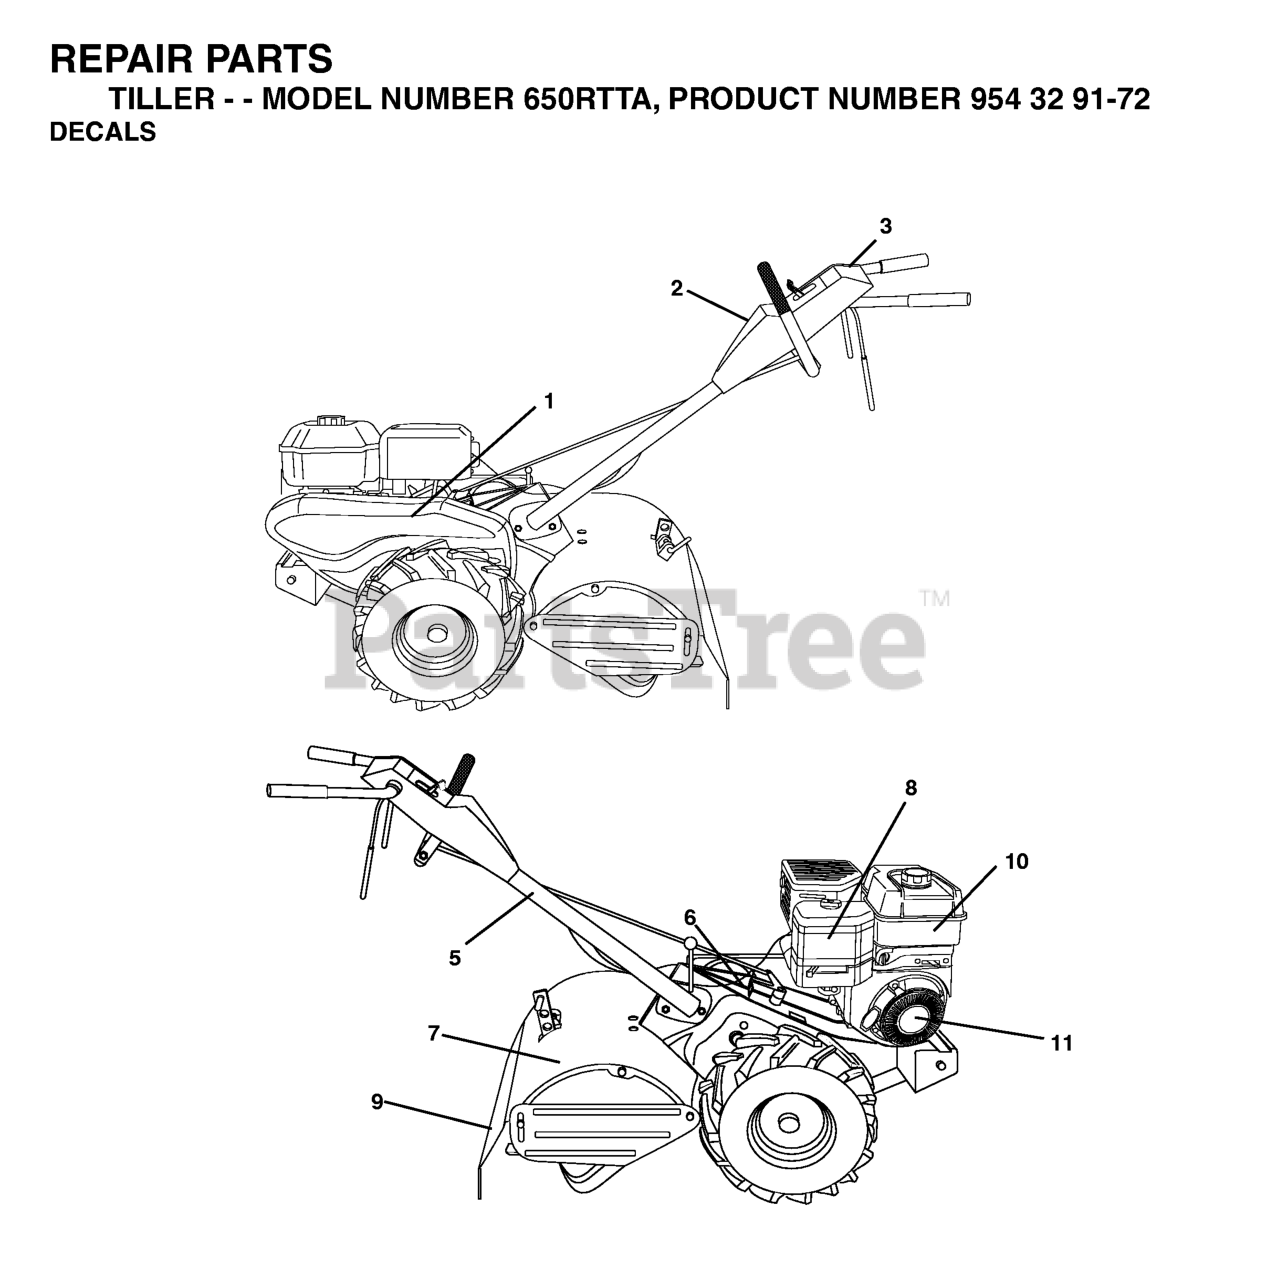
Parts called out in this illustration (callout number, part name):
3	DECAL.CONTROL.TINE.SPLIT LOOP
5	DECAL TI (2 2)
6	DECAL.SHIFT.INDICATOR.TILLER
7	DECAL -CAUTION
8	DECAL, ENG. B&S 6.5HP
9	DECAL TI
10	DECAL, ENGINE INTEK REF
11	DECAL.REWIND
